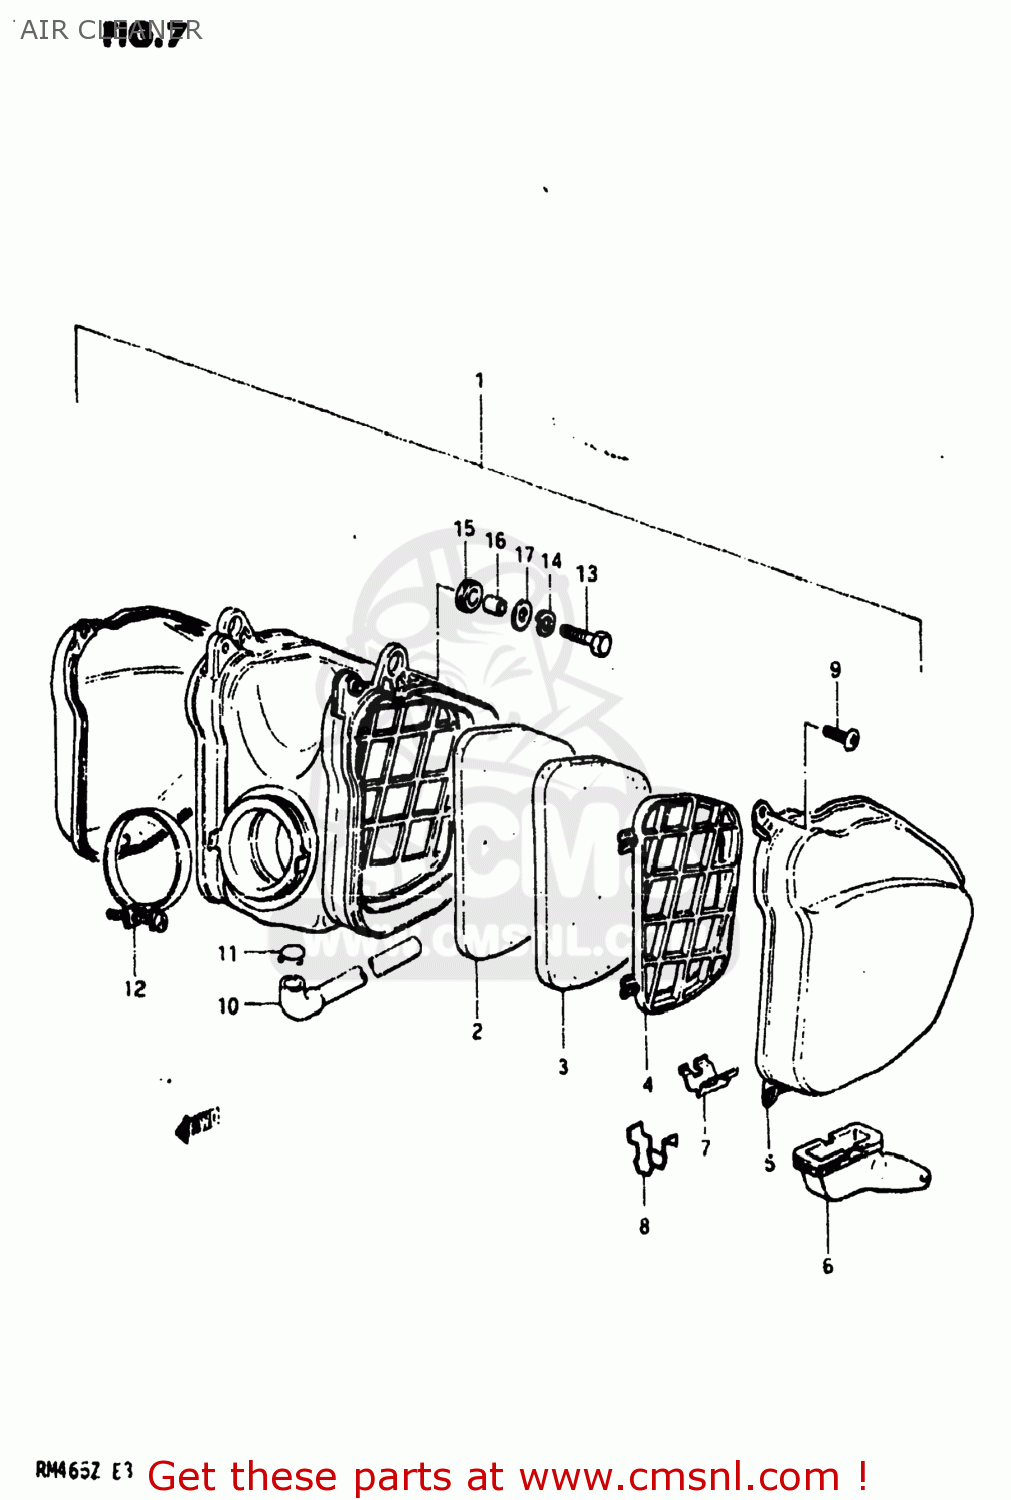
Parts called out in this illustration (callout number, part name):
1	CLEANER ASSEMBLY,AIR
2	FILTER
3	FILTER,2ND
4	HOLDER,FILTER
5	CAP,AIR CLEANER
6	DRAIN TUBE
7	DRAIN STOPPER
8	DRAIN STOPPER
9	SCREW
10	DRAIN TUBE
11	CLIP
12	CLAMP
13	BOLT
14	LOCK WASHER
15	CUSHION
16	SPACER (7X9X7)
17	WASHER
